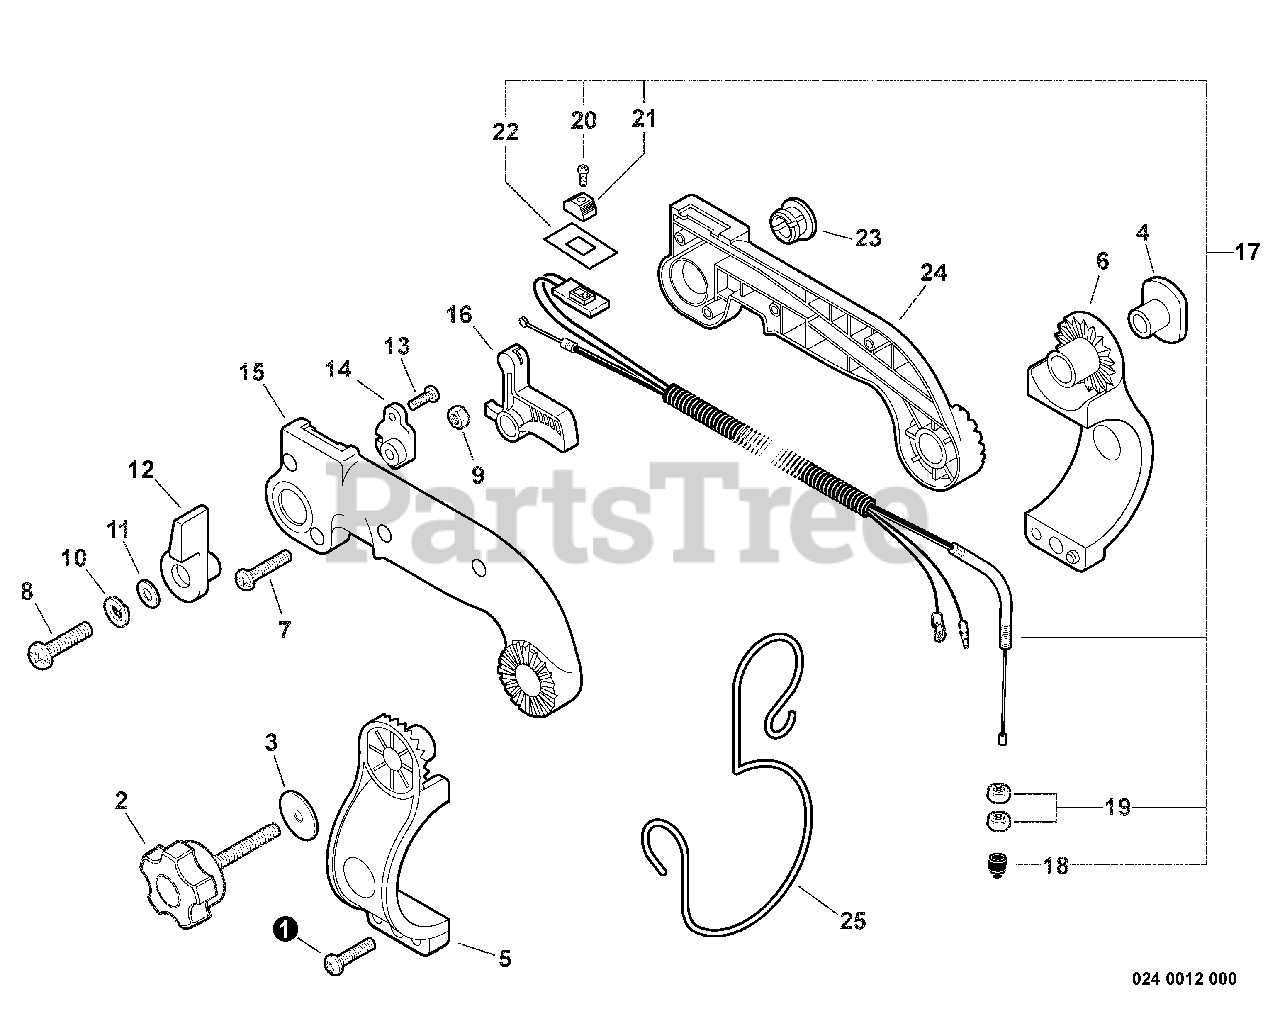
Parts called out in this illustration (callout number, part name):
1	SCREW - 5X20 -- TAPPING
2	THUMBSCREW
3	WASHER - 6
5	BRACKET, HANDLE - LEFT
6	BRACKET, HANDLE - RIGHT
7	SCREW - 4X22
8	SCREW - 6X20
9	LOCKNUT - 6
10	LOCKWASHER - 6
11	WASHER - 6
12	CONTROL, THROTTLE
13	SCREW - 4X10
14	BRACKET, THROTTLE
15	HANDLE, CONTROL - LEFT
16	TRIGGER, THROTTLE
17	CONTROL CABLE ASSY
18	CAP, DUST
20	SCREW - 3X10
21	KNOB, SWITCH - ORANGE
22	COVER, SWITCH - STOP
24	HANDLE, CONTROL - RIGHT
